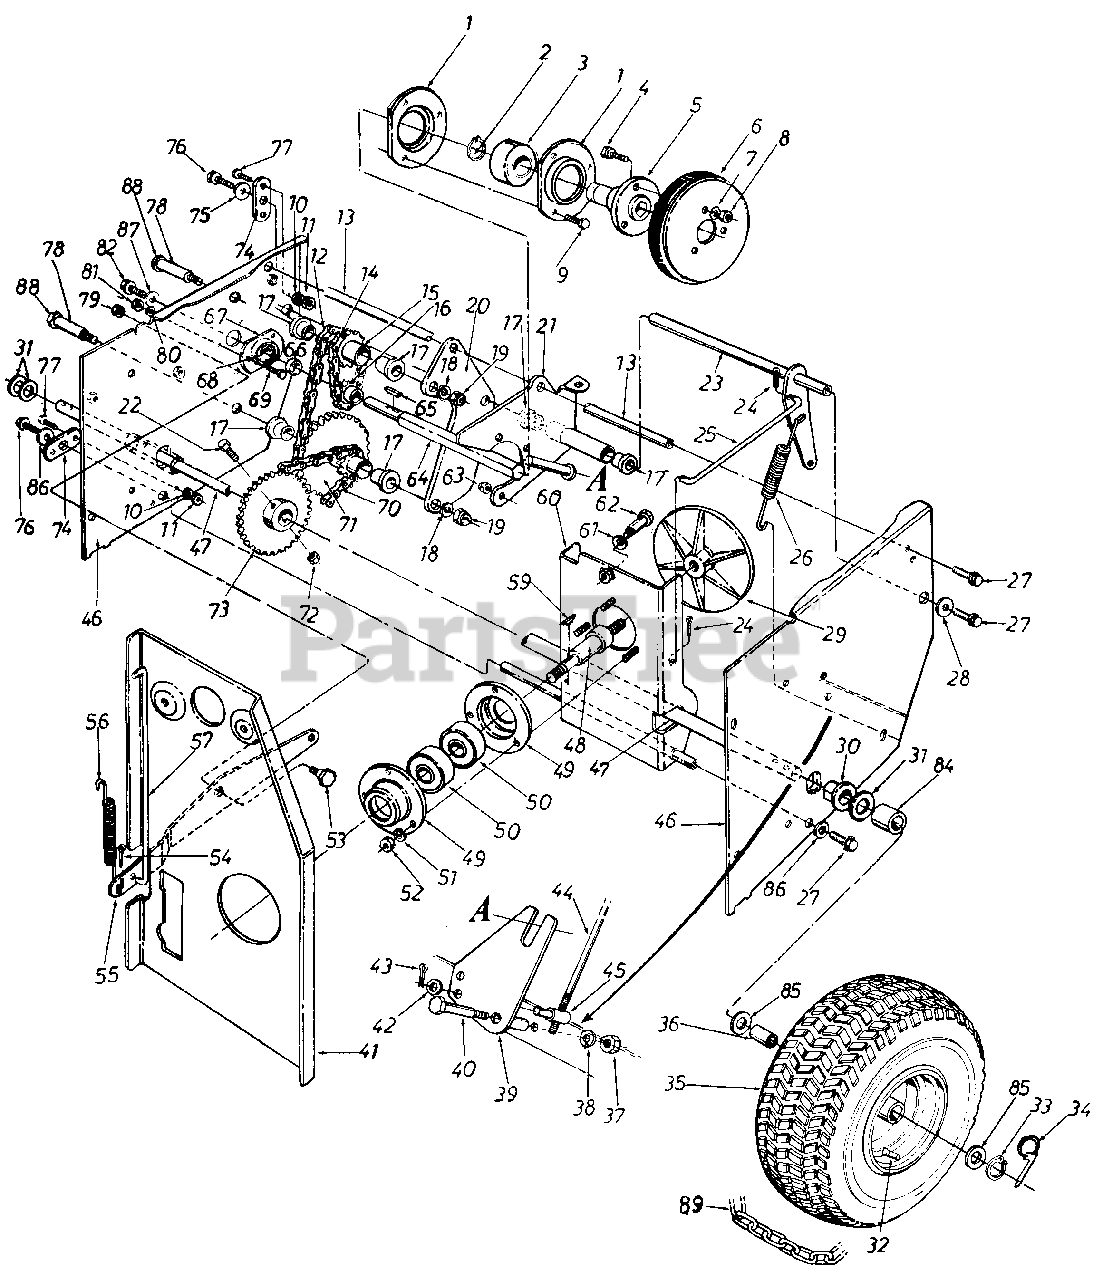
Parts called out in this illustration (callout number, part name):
1	Bearing Housing
2	Snap Ring 1.0" Dia.
3	Ball Brg. .25MM x 52MM x 15MM Thk.
4	Hex Sems Bolt 5/16-18 x .75" Lg. *
5	Friction Wheel Adapter
6	Friction Wheel Ass'y.
7	L-Wash. 5/16" I.D.*
8	Hex Nut 5/16-18 Thd.*
9	Hex Bolt 1/4-28 x .62" Lg.*
10	L-Wash. 1/4" I.D.*
11	Hex Nut 1/4-20 Thd.*
12	#41 Chain 1/2" Pitch x 43 Links
13	Sliding Support Axle
14	#41 Chain 1/2" Pitch x 19 Links
15	9 and 14 Teeth Sprocket Hub Ass'y.
16	8 Teeth Sprocket
17	Flange Bearing .63" I.D.
18	L-Wash. 3/8" I.D. H.D.
19	Hex L-Jam Nut 3/8-24 Thd.
22	Hex Bolt 1/4-28 x 1.5" Lg.
23	Drive Clutch Brkt. Ass'y.
24	Inter. Cot. Pin 5/16" Dia.*
25	Drive Clutch Rod .31" Dia. x 7.38" Lg.
26	Extension Spring 4.31" Lg.
27	Hex L-Bolt 5/16-18 x .62"
28	Fl-Wash. .345" I.D. x .75" O.D.
29	Aluminum Drive Plate
30	Flange Brg. w/Flats
31	Fl-Washer
32	Tubeless Air Valve
33	Snap Ring 3/4" Shaft
34	Klick Pin
35	Wheel Ass'y. Comp. 15 x 6
36	Bearing.75" I.D.
37	Hex Jam Nut 3/8-16 Thd.
38	L-Wash. 3/8" I.D.*
41	Enqine Brkt. Ass'v.
42	Fl-Wash. .344" I.D. x .62" O.D.
43	Cotter Pin 3/32" Dia. x .75" Lg.
44	Shifting Rod
45	Adjustment Ferrule
46	Frame Ass'y.
47	Free Wheeling Axle
48	Drive Plate Spindle
49	Bearing Housing
50	Ball Brg. .787" I.D. x 1.85" O.D.
51	L-Wash. 5/16" I.D.
52	Hex Nut 5/16-18 Thd.
53	Shld. Bolt .625" Dia. x .170" Lg.
54	Inter. Cotter Pin 5/16" Dia.
55	Auger Clutch Brkt.
56	Extension Spring .38" O.D. x 3.18" Lg.
57	Auger Clutch Rod .31" Dia. x 10.62" Lg.
59	#61 Hi-Pro Key 3/16" x 5/8" Dia.
62	Shld. Bolt
63	Hex Ins. Jam Nut 1/4-28 Thd.
64	Hex Shaft
65	#9 Hi-Pro Key 3/32" x 5/8" Dia.
66	Spacer.51" I.D. x .69" O.D.
67	Bearing Housing
68	Ball Bearing
69	Hex Bolt 1/4-20 x .62" Lg.
70	#420 Chain .50" Pitch x 29 Links
71	9 and 32 Teeth Sprocket Hub Ass'y.
72	Hex L-Nut 1/4-20 Thd.
73	22 Teeth Sprocket Hub Ass'y.
74	Pivot Axle Brkt.
75	Fl-Wash. .345" I.D. x .75"
76	Hex L-Bolt 5/16-18 x .62"
77	Hex Bolt 1/4-20 x .62" Lg.
78	Sprocket Hub Tubing 1.88"
79	Hex Cent. L-Nut 3/8-16 Thd.
80	L-Wash. 1/4" I.D.
81	Hex Nut 1/4-20 Thd.*
82	Hex L-Bolt 5/16-18 x .62"
84	Spacer.75" I.D.
85	Fl-Washer
86	Fl-Wash. .344" I.D. x .875"
87	Bell-Wash. .345" I.D. x .88"
88	Hex Bolt 3/8-24 x 2.75" Lg.
89	Tire Chain
